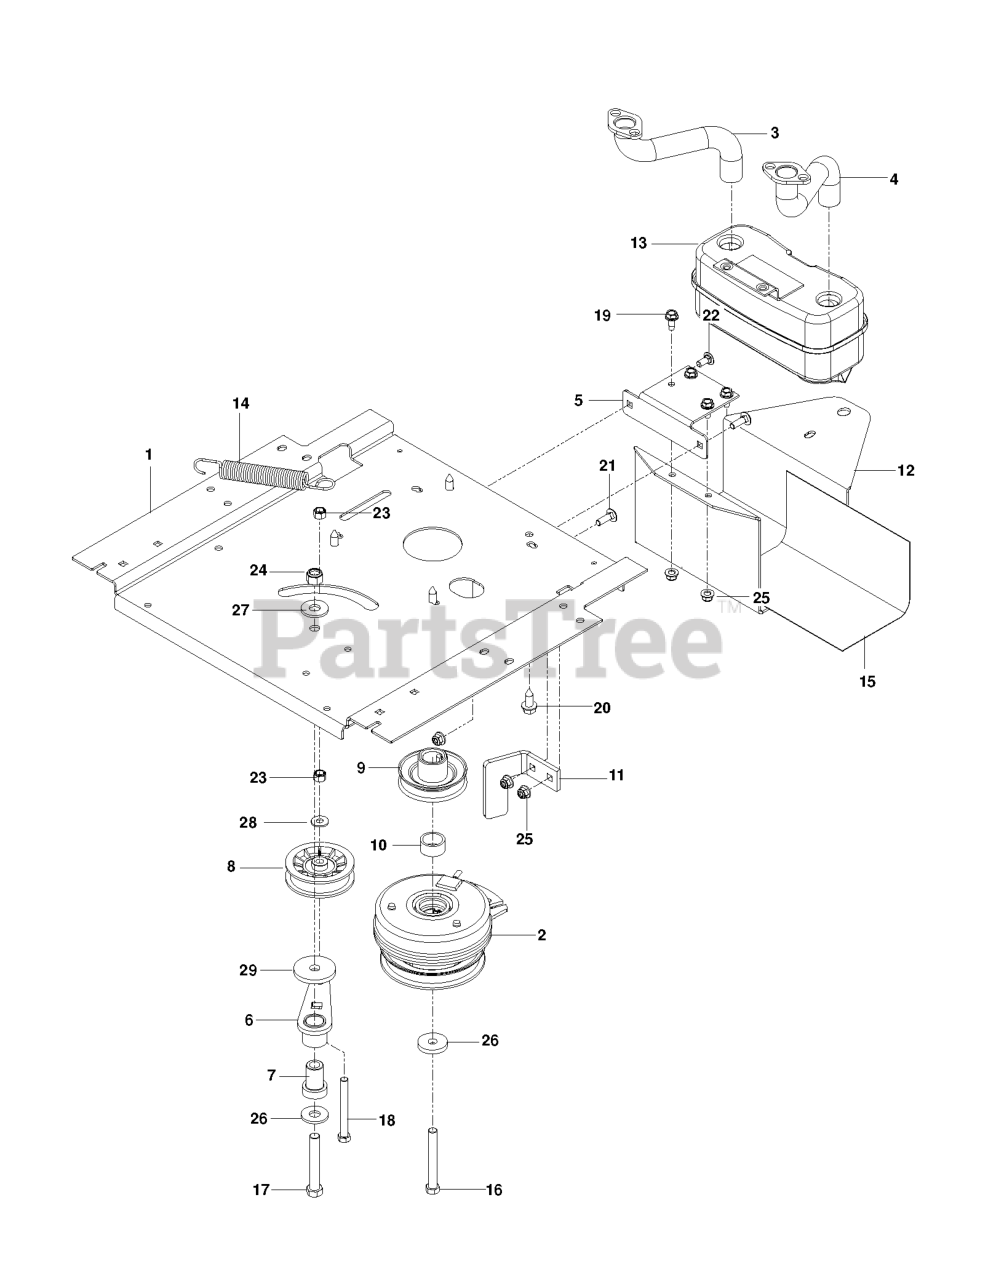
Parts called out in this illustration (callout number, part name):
1	PLATE, ENGINE BLK
2	Clutch, 105 Ft/Lb
3	Exhaust Tube, RH B&S Twin Intek
4	Exhaust Tube, LH.Bs/Twin
5	BRACKET, MUFFLER, BLACK
6	IDLER ARM
7	IDLER SPINDLE
8	PULLEY, IDLER
9	PULLEY, ENGINE
10	T & B SPACER
11	STOP, CLUTCH, BLACK
12	Muffler Guard
13	MUFFLER ASM TWIN
14	SPRING, DECK DRIVE
15	HEAT SHIELD
16	HCS 7/16-20X3-1/2 GR 5 ZN
17	HCS 1/2C X 3 1/4
18	HCS 3/8-16X3 1/2 GR5
19	BOLT 5/16-18 X 3/4
20	HHFS 3/8-16 X 1.0 THD FORMING
21	RHSNB 5/16C X 1
22	BOLT 5/16C X 3/4" CARRIAGE
23	NUT 3/8-16 NYLOC
24	NUT 1/2-13 HEX NYLOC ZD
25	5/16-18 NYLOC FLANGE NUT
26	CLUTCH, WASHER
27	WASH USS FLAT 1/2
28	WASHER 5/16 FLAT
29	HEAVY WASHER
